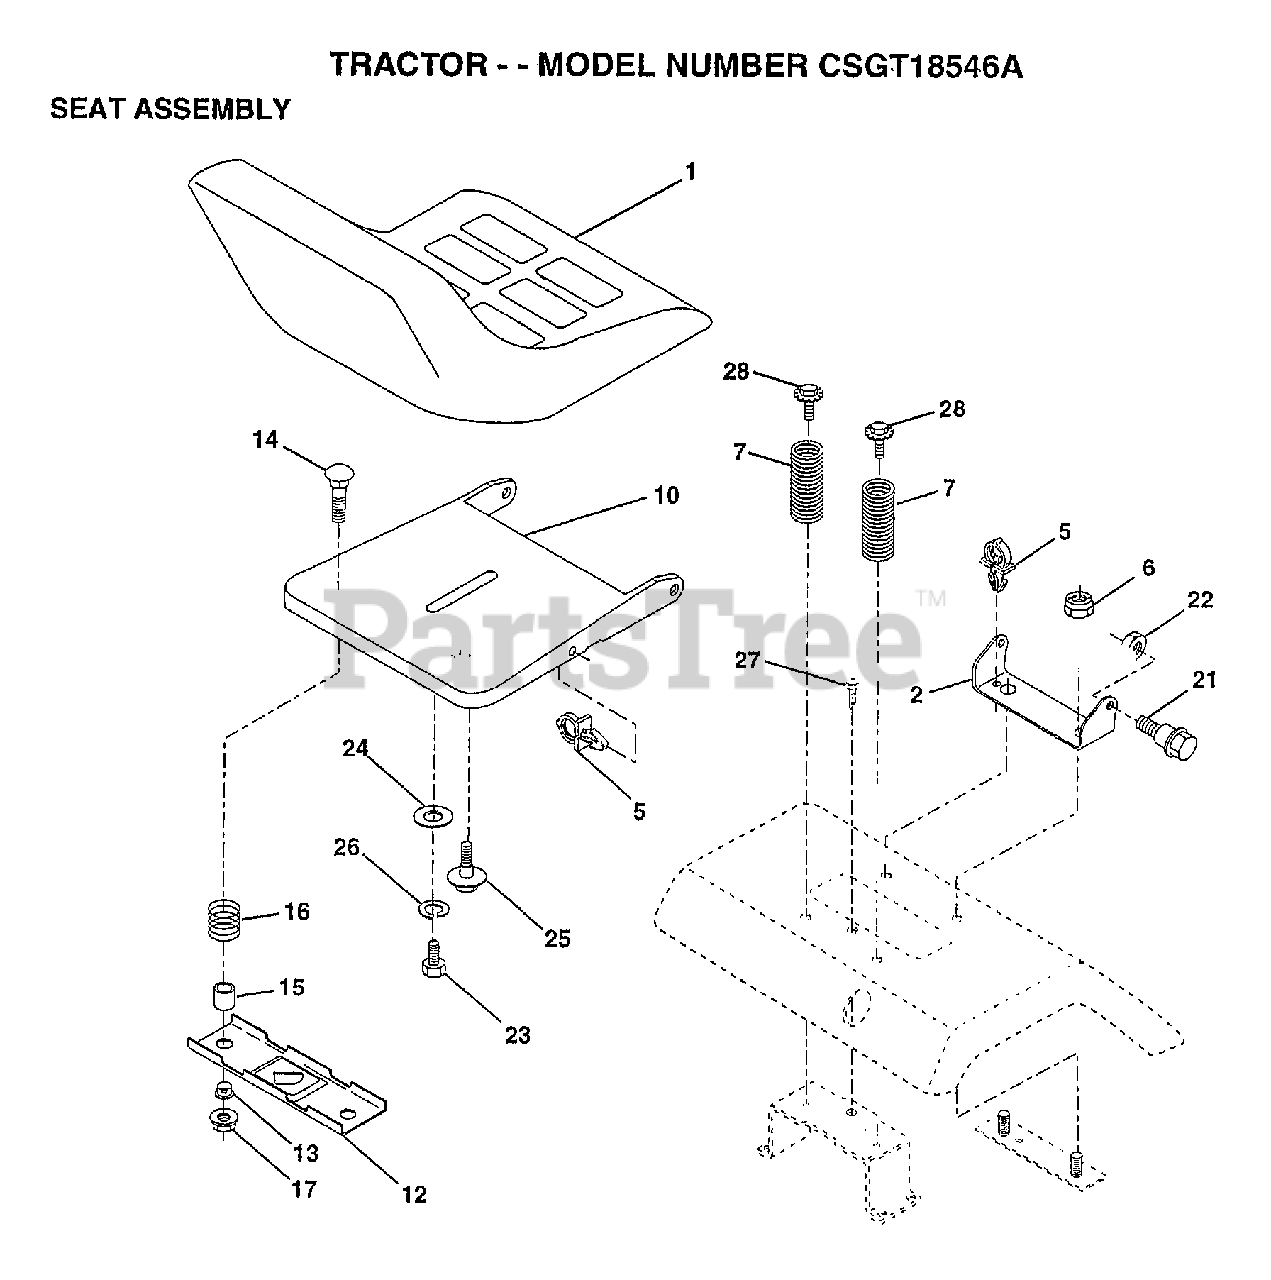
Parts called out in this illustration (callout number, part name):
2	BRACKET PVT SEAT
5	CLIP.PUSH-IN.HING
6	NUT
7	SPRING COMPRESSIO
10	PAN-SEAT
12	BRKT SWITCH
13	BUSHING
15	SPACER SPLIT
16	SPRING COMPRESSED
21	"BOLT,SHOULDER"
22	NUT
23	BOLT
24	WASHER
25	"BOLT,SHOULDER"
26	LOCKWASHER
27	SCREW LT
28	BOLT.5/16-18.UNC
